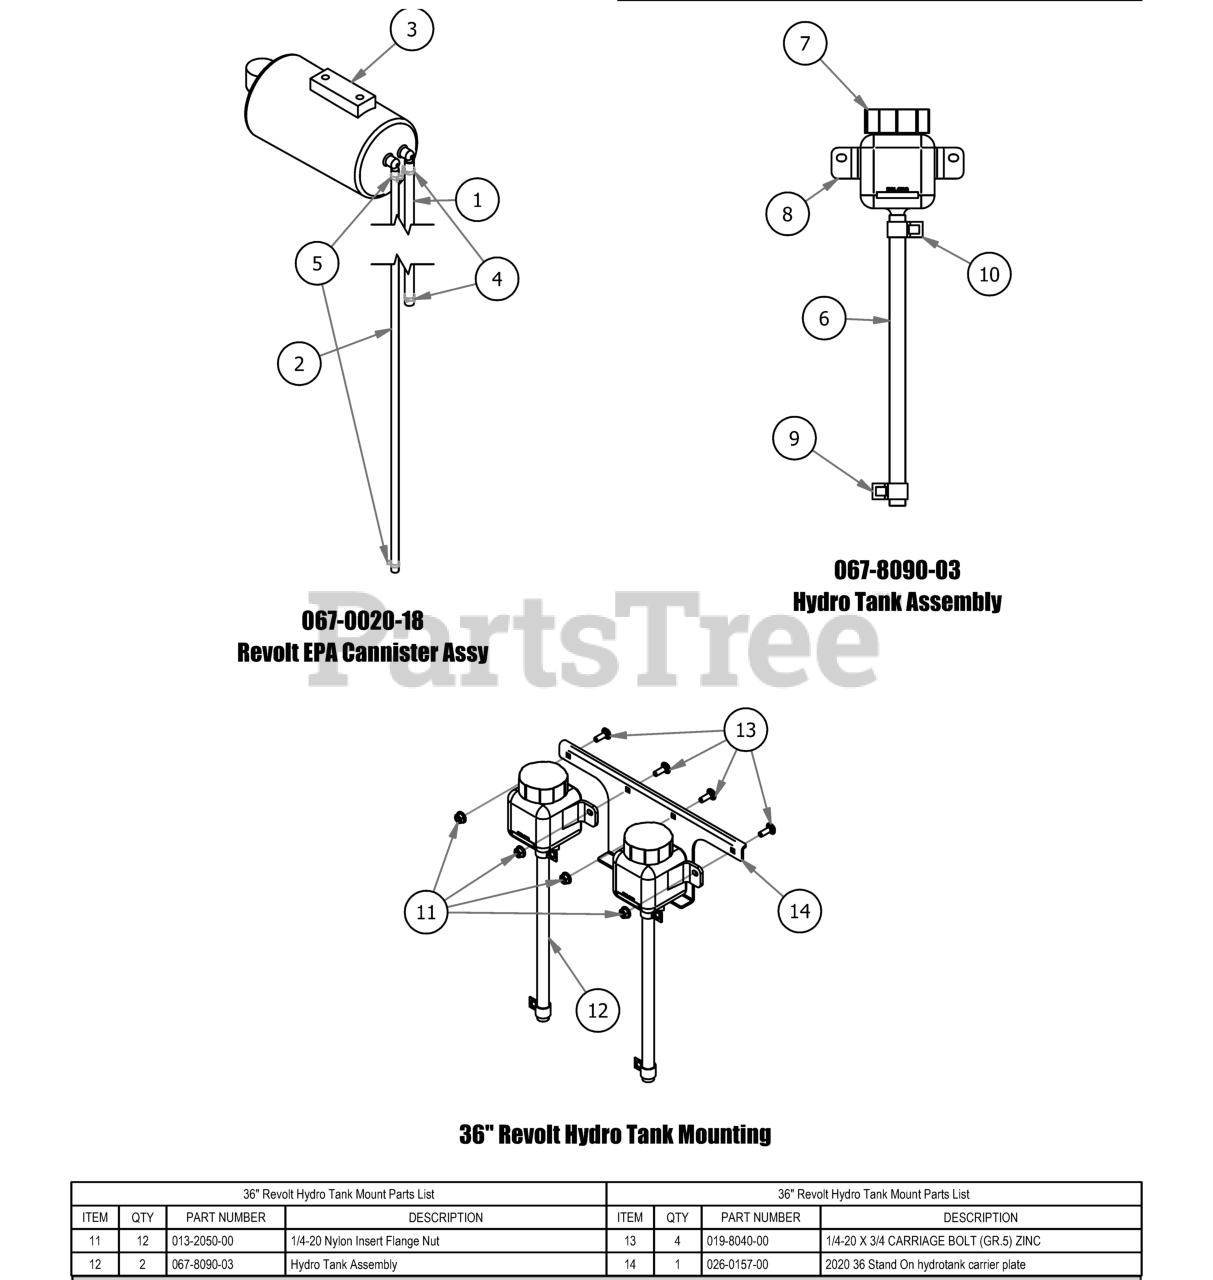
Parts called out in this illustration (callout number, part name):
1	1/4" Vinyl Tubing
2	3/16" Vinyl Tubing, 55" Long
3	Carbon Canister
4	3/16 Vinyl Clamp
5	3/16" Vinyl Hose Clamp
6	ZT/Maverick Hydro Tank Hose
7	Hydraulic Tank Cap
8	350ml Expansion Tank
9	3/8" Hose Clamp
10	1/2 Hose Clamp
11	1/4-20 Nylon Insert Flange Nut
12	Hydro Tank Assembly
13	1/4-20 X 3/4 CARRIAGE BOLT (GR.5) Zinc
14	2020 36 Stand On hydrotank carrier plate
